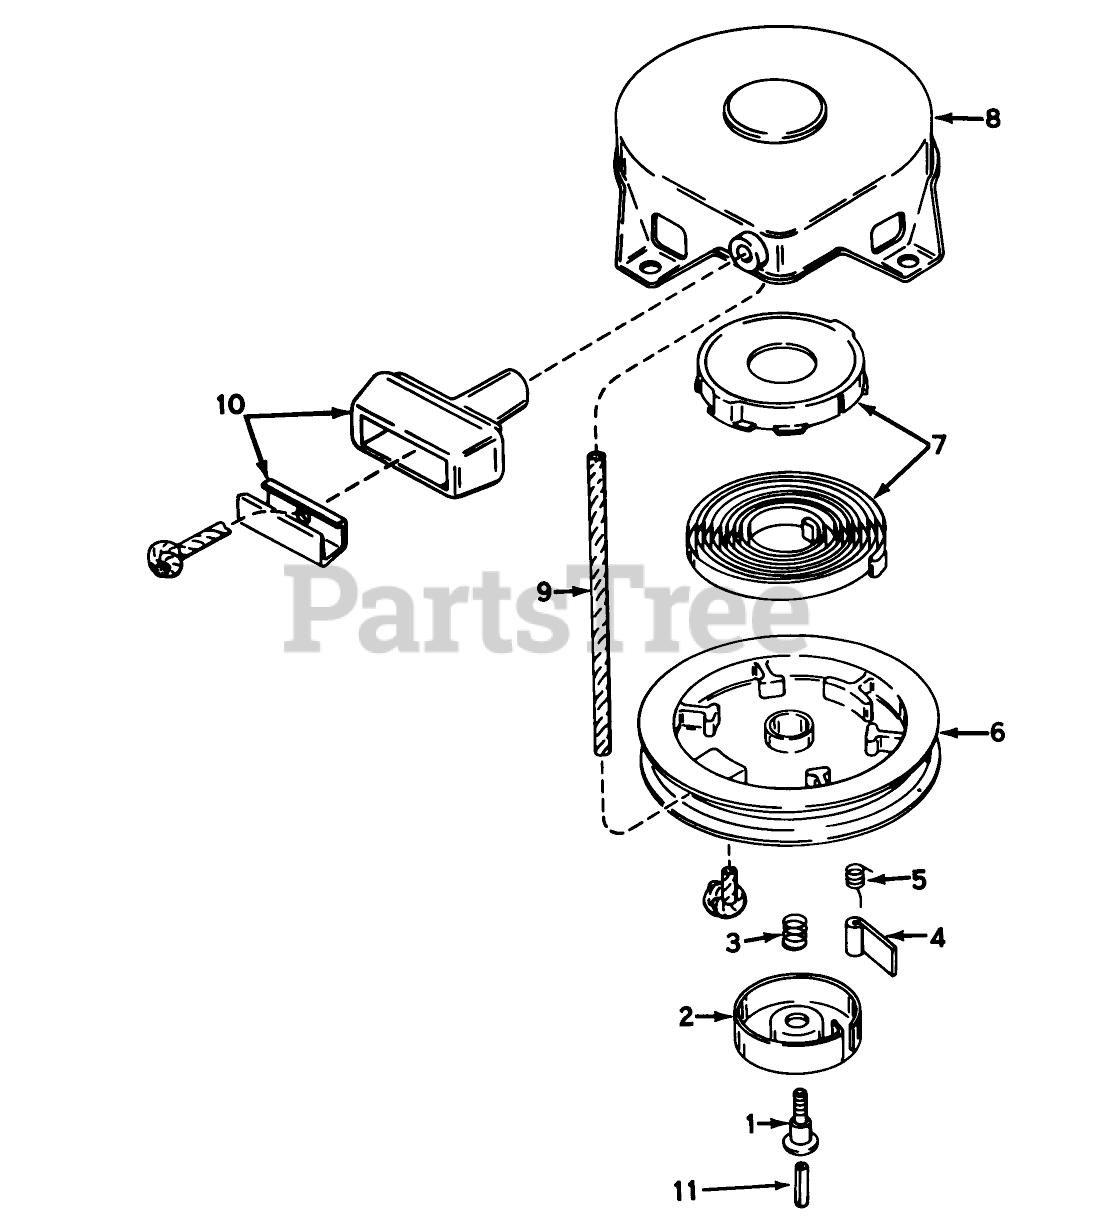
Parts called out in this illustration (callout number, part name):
1	Screw
2	Retainer
3	Spring-Brake
4	Dog-Starter
5	Spring-Dog
6	Pulley
7	Spring Keeper Assy
8	STARTER HOUSING ASSY
9	Rope Starter
10	Assy., Starter
11	Centering
